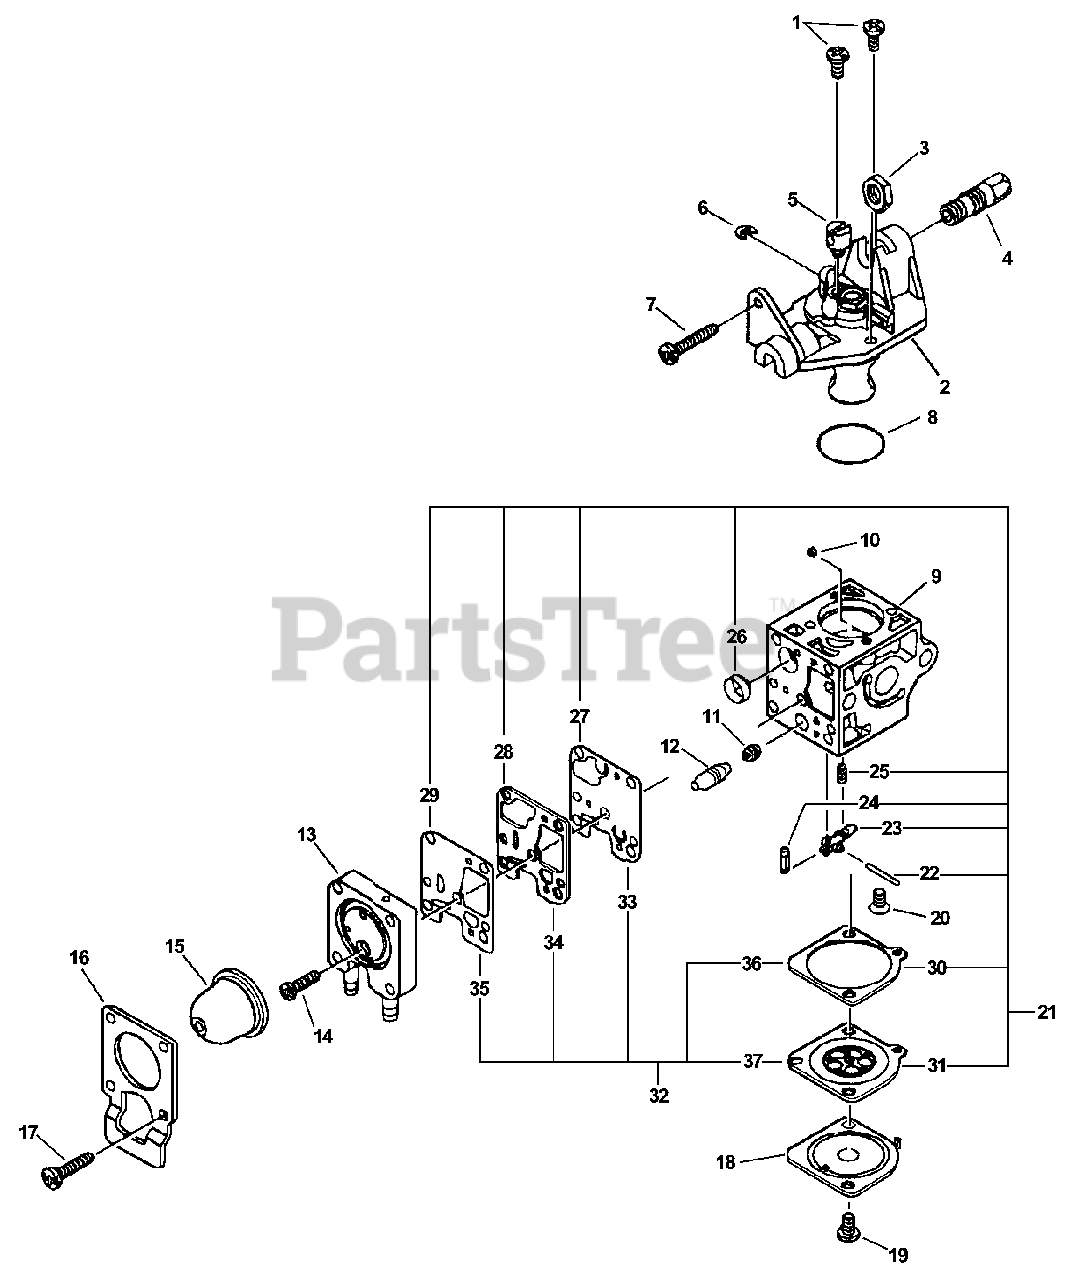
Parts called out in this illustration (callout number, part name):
2	ROTOR COVER ASSY
4	NUT, CABLE ADJUST
6	RING, RETAINING
7	SCREW, IDLE ADJUST
9	BODY, CARBURETOR
10	GUIDE, ROLLER
12	PLUG KIT
13	BASE, PURGE
14	SCREW, PURGE BASE
15	BULB, PURGE
16	RETAINER, PURGE BULB
17	SCREW, RETAINER
18	COVER, METERING
20	SCREW, METERING LEVER PIN
21	REPAIR KIT
22	PIN, METERING LEVER
23	LEVER, METERING
24	VALVE, INLET NEEDLE
25	SPRING, METERING LEVER
26	STRAINER
27	DIAPHRAGM, PUMP
28	GASKET, PUMP
29	DIAPHRAGM, SURGE
30	GASKET, DIAPHRAGM
31	DIAPHRAGM, METERING
32	DIAPHRAGM/GASKET KIT
33	DIAPHRAGM, PUMP
34	GASKET, PUMP
35	DIAPHRAGM, SURGE
36	GASKET, DIAPHRAGM
37	DIAPHRAGM, METERING
